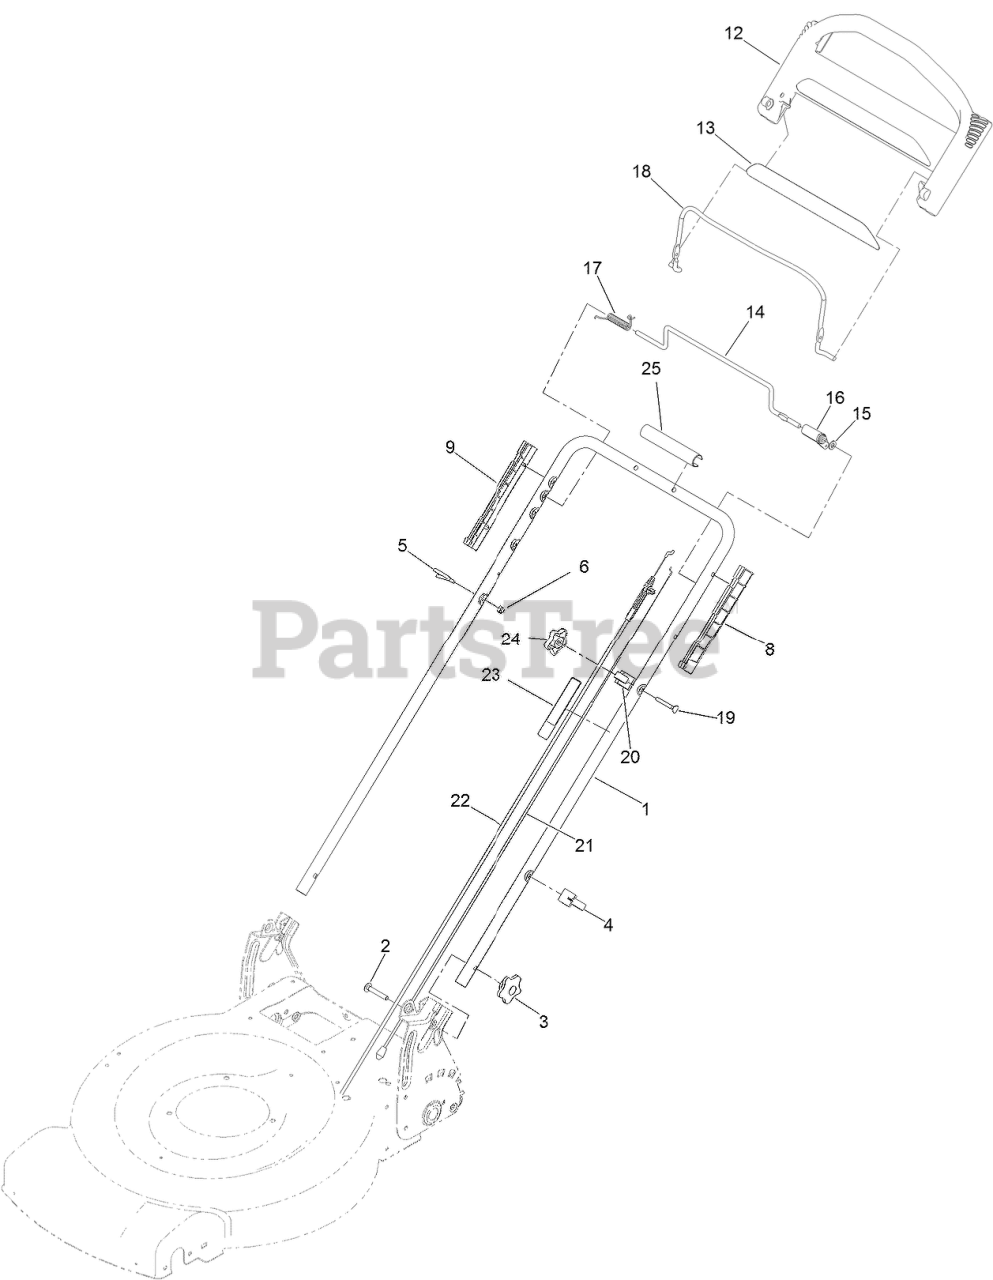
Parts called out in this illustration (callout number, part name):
2	Screw-CARR
3	KNOB-HANDLE
4	GUIDE-CABLE
5	GUIDE-ROPE
6	NUT-LOCK, NI
8	GUIDE-LH
9	GUIDE-RH
12	HANDLE-CONTROL
14	BAR-CONTROL, TRACTION
15	WASHER-PLAIN
16	LEVER-TRACTION
17	Spring-Torsion
18	Bail-Brake
19	SCREW
20	ANCHOR-CABLE
21	CABLE-TRACTION
22	CABLE-BRAKE
23	DECAL-TRACTION, ADJUST
24	KNOB-HANDLE, LOCKING
25	HANDLE-COVER
